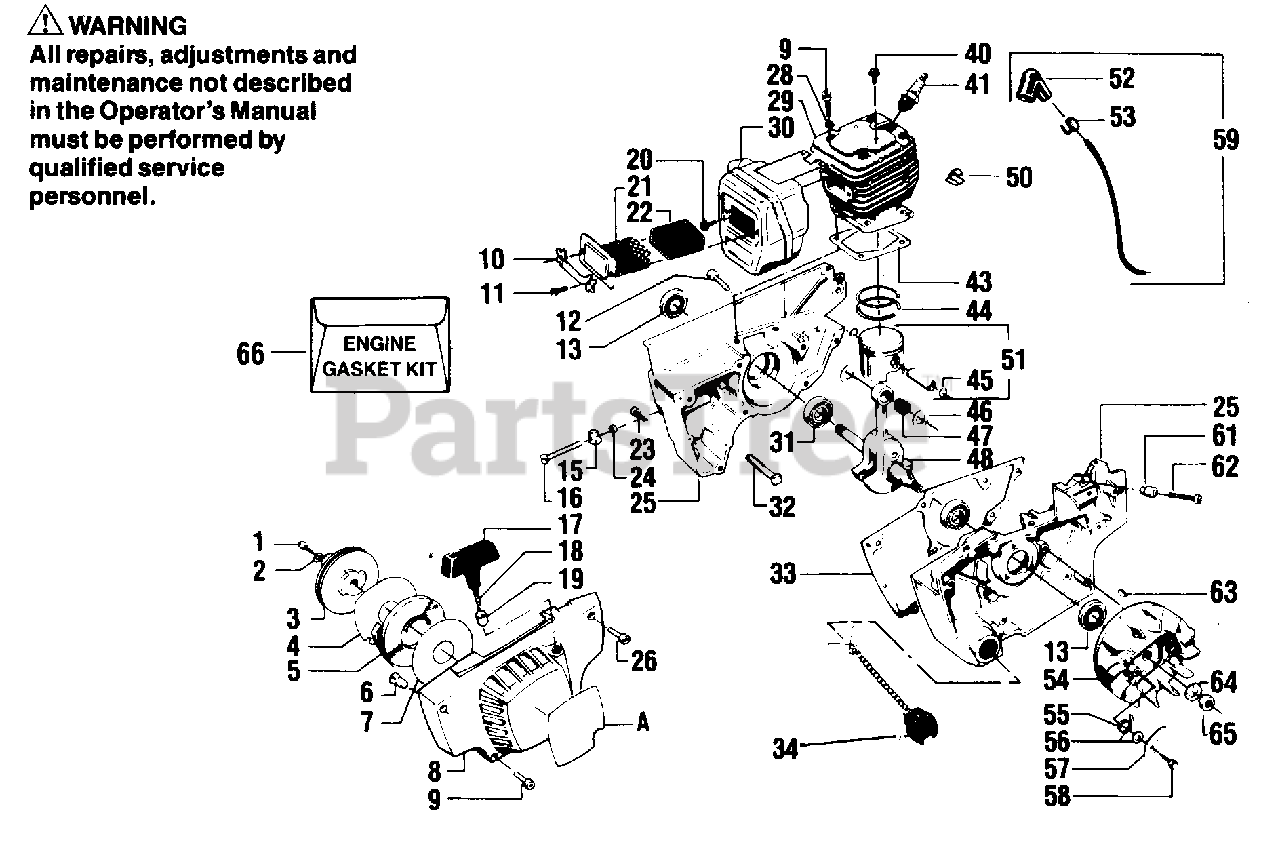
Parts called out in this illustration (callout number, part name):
1	Screw - 1/4 - 20 x 1/2 - Socket Hd.
2	Washer - Starter Pulley
3	Pulley Starter
4	Disc. - Starter - Top
5	Spring - Starter Rewind
6	Pin - Starter Anchor
7	Disc. - Starter - Bottom
8	Fan Housing Assembly (Incl. #6 & 19)
9	Screw - 3 - 1/4 - 20 Soc. Hd. - Fan Hsg. & Cylinder
10	Retainer - Diffuser Mounting Screw
11	Screw - 10 - 32 x 1/2 - Slotted Hex Hd.
12	Screw - Crankcase #10 - 24 x 3/4 - Soc. Hd.
13	Seal - Crankshaft
15	Pin - Bar Adjusting
16	Screw - Bar Adj. - #10 - 24 x 2-3/16
17	Handle - Starter Rope
18	Rope Kit
19	Bushing - Rope Grommet
20	Screw - Muffler Mtg. - #12 - 24 x 5/8
21	Diffuser - Muffler
22	Screen - Spark Arrestor
23	Screw - #6 - 40 x 1/2 - Soc.
24	Nut - Bar Adj. - #10 - 24 - Self Locking
25	Crankcase Assembly (Incl. #13, 15, 16, 24, 31, 32 & 33)
26	Screw - Fan Hsg. Mtg. - 1/4 - 20 x 1-1/2 Soc. Hd.
28	Lockwasher - Cylinder
29	Cylinder
30	Ass'y. Muffler
31	Bearing - Crankshaft
32	Kit - Bar Stud Replacement (3/8")
33	Gasket - Crankcase
34	Oil Cap Ass'y. (Incl. O-Ring)
40	Screw - Muffler Mtg. #10 - 24 x 3/8
41	Spark Plug (CJ-6)
43	Gasket - Cylinder
44	Piston Ring
45	Retainer - Piston Ring
46	Washer - Thrust (Rod Top)
47	Bearing - Top Rod
48	Crankshaft & Rod Ass'y.
50	Clip - High Tension Lead
51	Kit - Piston Ass'y. - (Incl. #45 & pin)
52	Boot - Spark Plug
53	Connector - Spark Plug
54	Flywheel
55	Spring - Starter Dog
56	Washer - Starter Dog
57	Dog - Starter
58	Stud - Starter Dog
59	High Tension Lead Ass'y. - Ignition (Incl. #52 & 53)
61	Sleeve - Idle Screw Locking
62	Screw Adj. - Idle Speed
63	Key - Flywheel
64	Washer - Flywheel Mtg. - 3/8
65	Locknut - Flywheel Mtg. - 3/8 - 24
66	Engine - Gasket Kit (inc. 33,43)
A	Decal Fan Housing
